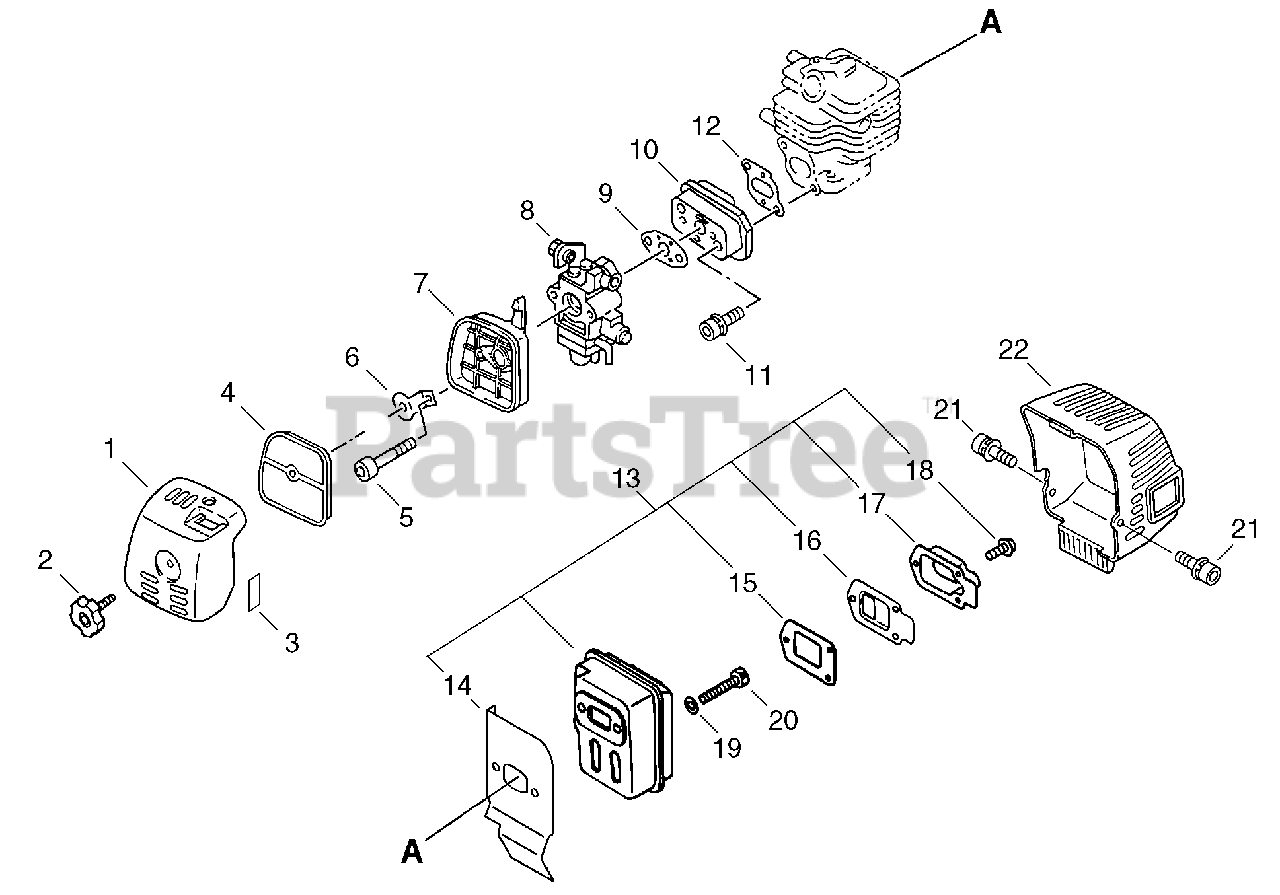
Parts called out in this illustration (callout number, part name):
1	COVER, AIR FILTER
2	THUMBSCREW
3	LABEL - CHOKE
4	FILTER, AIR - HEAVY DUTY
5	SCREW - 5X55
6	PLATE, PREVENT
7	CASE, AIR FILTER
8	CARBURETOR WYJ-192A
9	GASKET, INTAKE
10	INSULATOR, INTAKE
11	SCREW - 5X25
12	GASKET, INTAKE
13	MUFFLER ASSY
14	SHIELD, EXHAUST
15	GASKET, EXHAUST
16	GASKET, EXHAUST - INNER
17	GUIDE, EXHAUST - OUTER
18	SCREW - 4X10
19	WASHER - 5
20	SCREW - 5X55
21	SCREW - 5X12
22	COVER, EXHAUST
